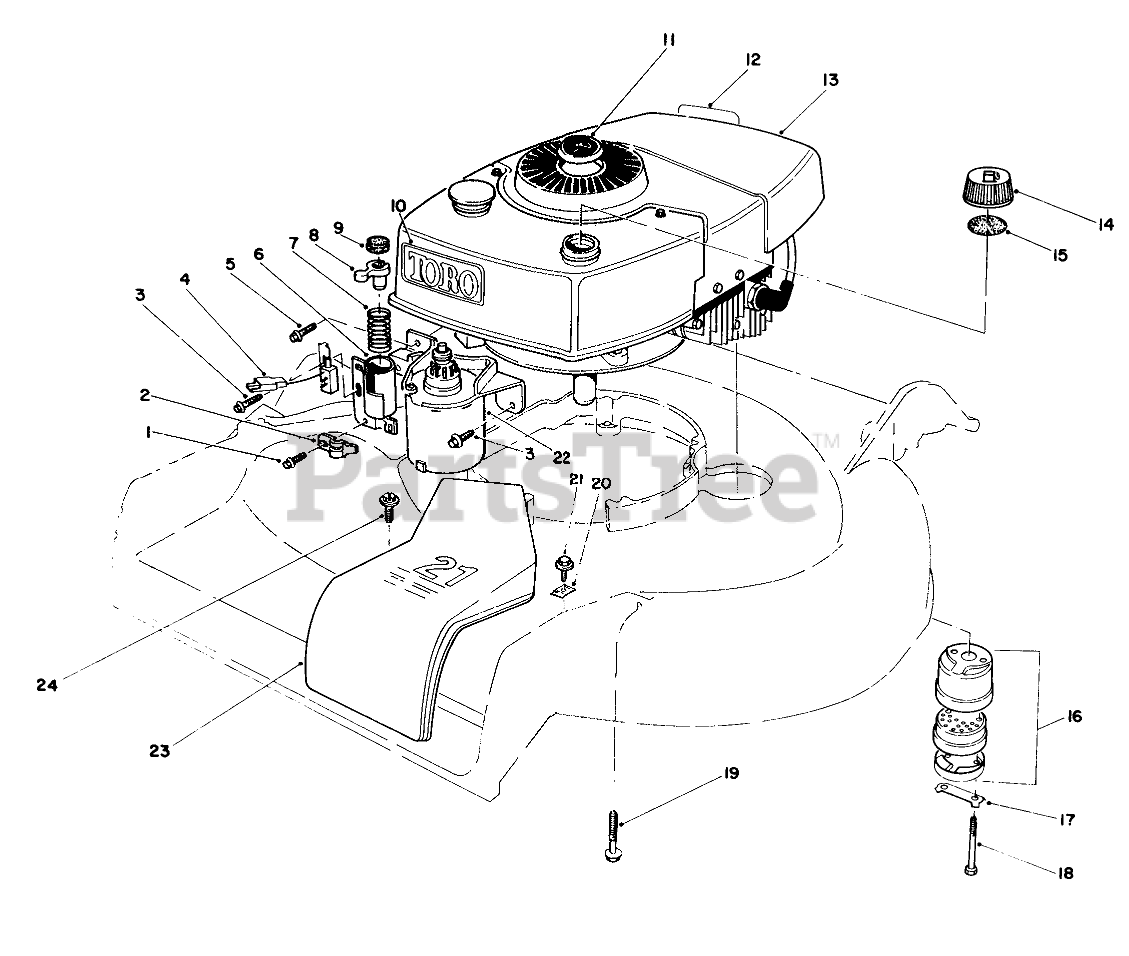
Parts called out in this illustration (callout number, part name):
1	SCREW
2	Clamp-Cable
3	SCREW
4	Support Seat
5	Screw
6	TUBE W A
7	COMPRESSION SPRING
8	Plunger
9	Pad-Friction
10	Decal Tow
11	PLUG BUTTON
12	Decal-Maintenan
13	Engine
14	Gas Cap Assembly (Incl. Ref. #15)
15	GAS CAP GASKET
16	Muffler Assembly (Incl. Ref. #17 & 18)
17	CLIP - LOCKING
18	SCREW-HH
19	3/8-16 X 2-3/4 CAPSCR
20	Cable Clamp
21	SCREW-HWHTF
22	STARTER MOTOR ASM
23	BELT COVER 21" S D
24	SCREW
